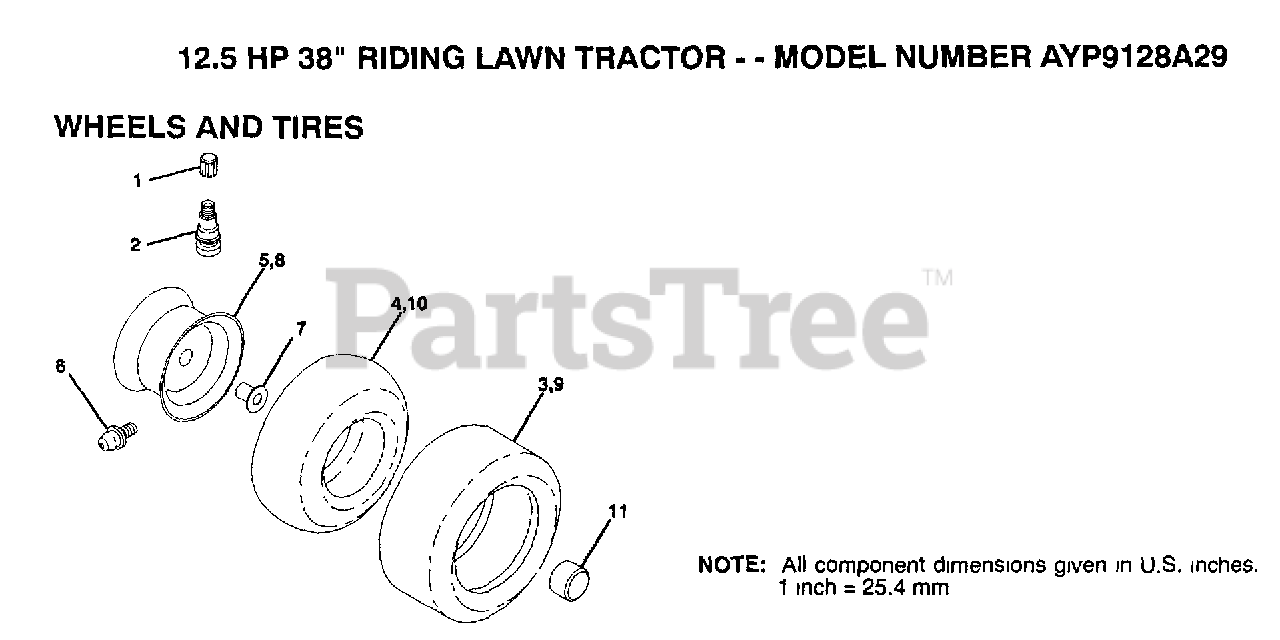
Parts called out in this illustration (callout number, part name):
1	VALVE CAP
2	VALVE STEM LT
4	TUBE.5.3/4.5/6
6	FITTING LT
7	"FLANGE, BEARING"
10	TUBE.18X9.5-8
11	HUB CAP
